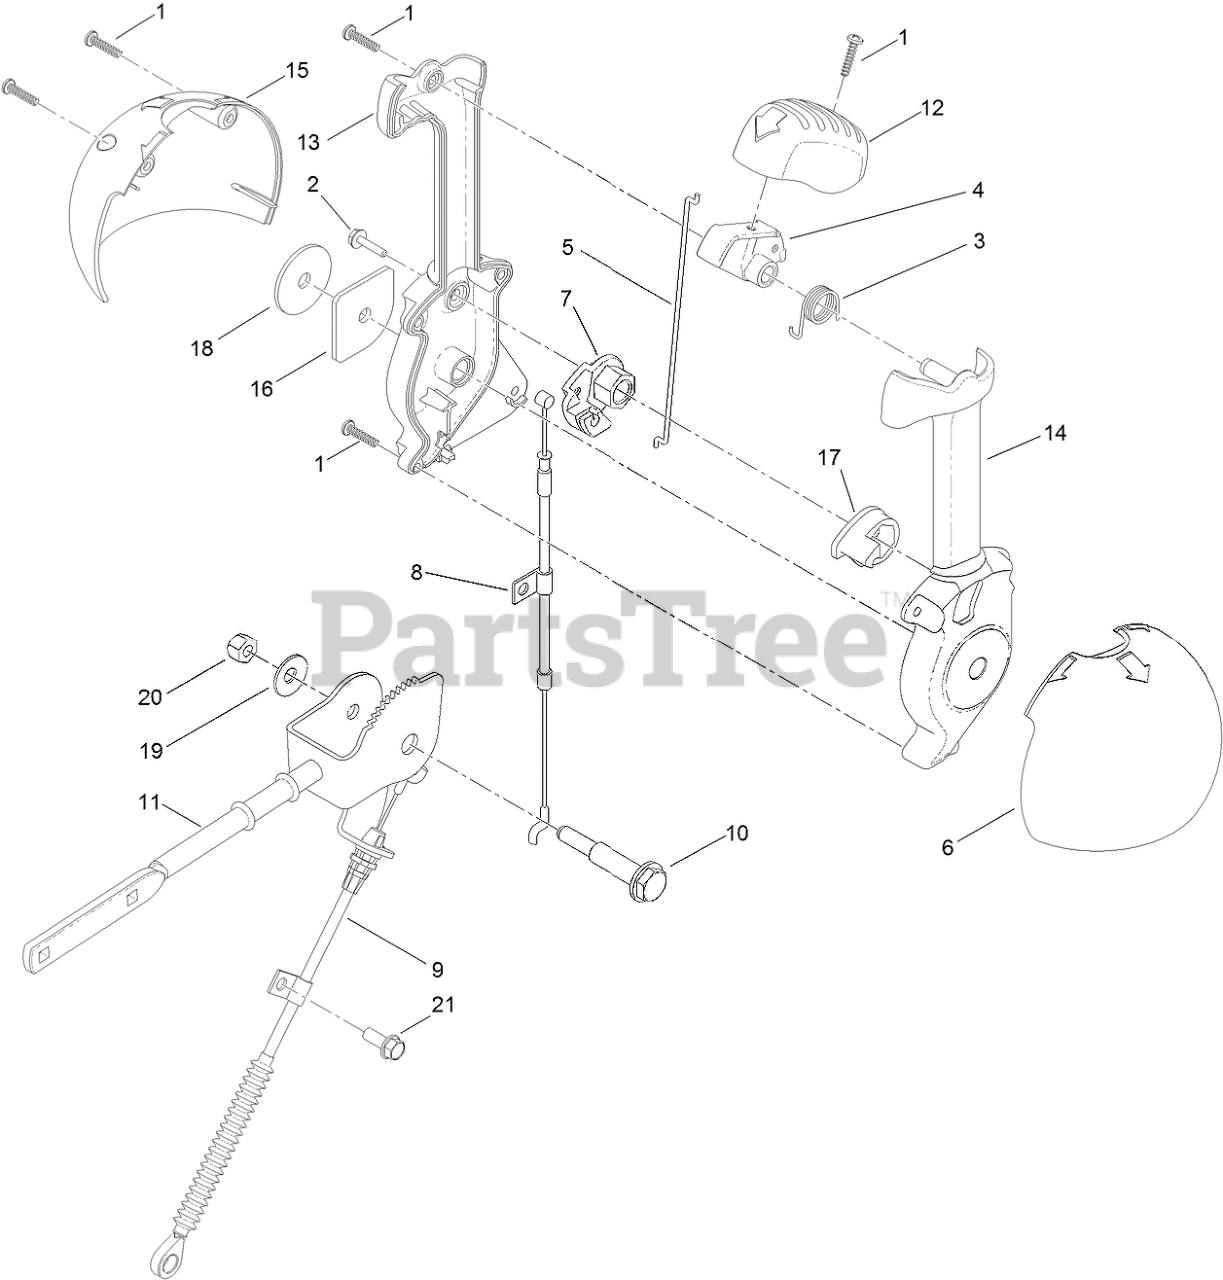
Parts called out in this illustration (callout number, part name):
1	SCREW-PPH
2	SCREW-HWH
3	SPRING-TORSION
4	TRIGGER-LATCH
5	LINK-LATCH
6	COVER-LEVER, CHUTE (LH)
7	LEVER-CABLE, DEFLECTOR
8	CABLE-RELEASE, CHUTE
9	CABLE-CONTROL, DEFLECTOR
10	SCREW-SHOULDER
11	ROD-CONTROL, CHUTE
12	CAP-LEVER
13	LEVER-CONTROL, CHUTE (RH)
14	LEVER-CONTROL, CHUTE (LH)
15	COVER-LEVER, CHUTE (RH)
16	PLATE-FRICTION
17	PAWL-LATCH
18	WASHER-NYLON
19	WASHER-BELLEVILLE
20	NUT-LOCK, NI
21	SCREW-HWH
